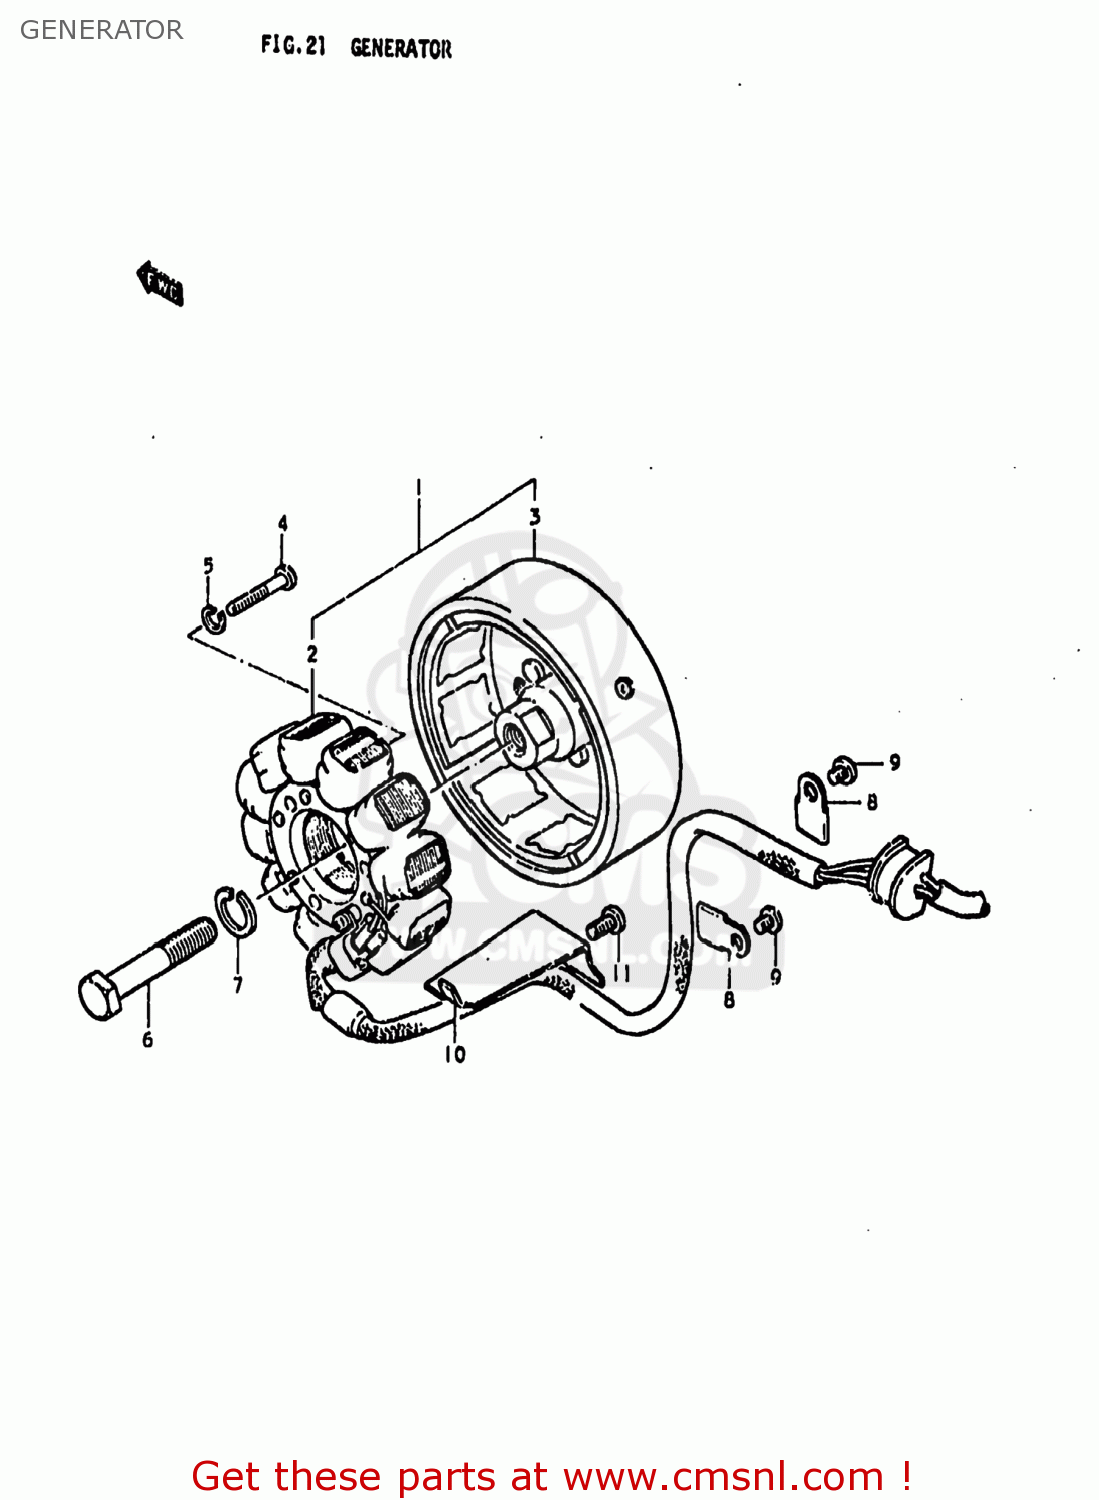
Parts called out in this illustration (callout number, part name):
1	GENERATOR ASSEMBLY
2	STARTER ASSY
3	ROTOR ASSEMBLY
4	SCREW
5	LOCK WASHER
6	BOLT 12X45
7	WASHER,LOCK 12
8	CLAMP,GENERATOR LEAD WIRE
9	SCREW
10	CLAMP,GENERATOR LEAD WIRE
11	SCREW
